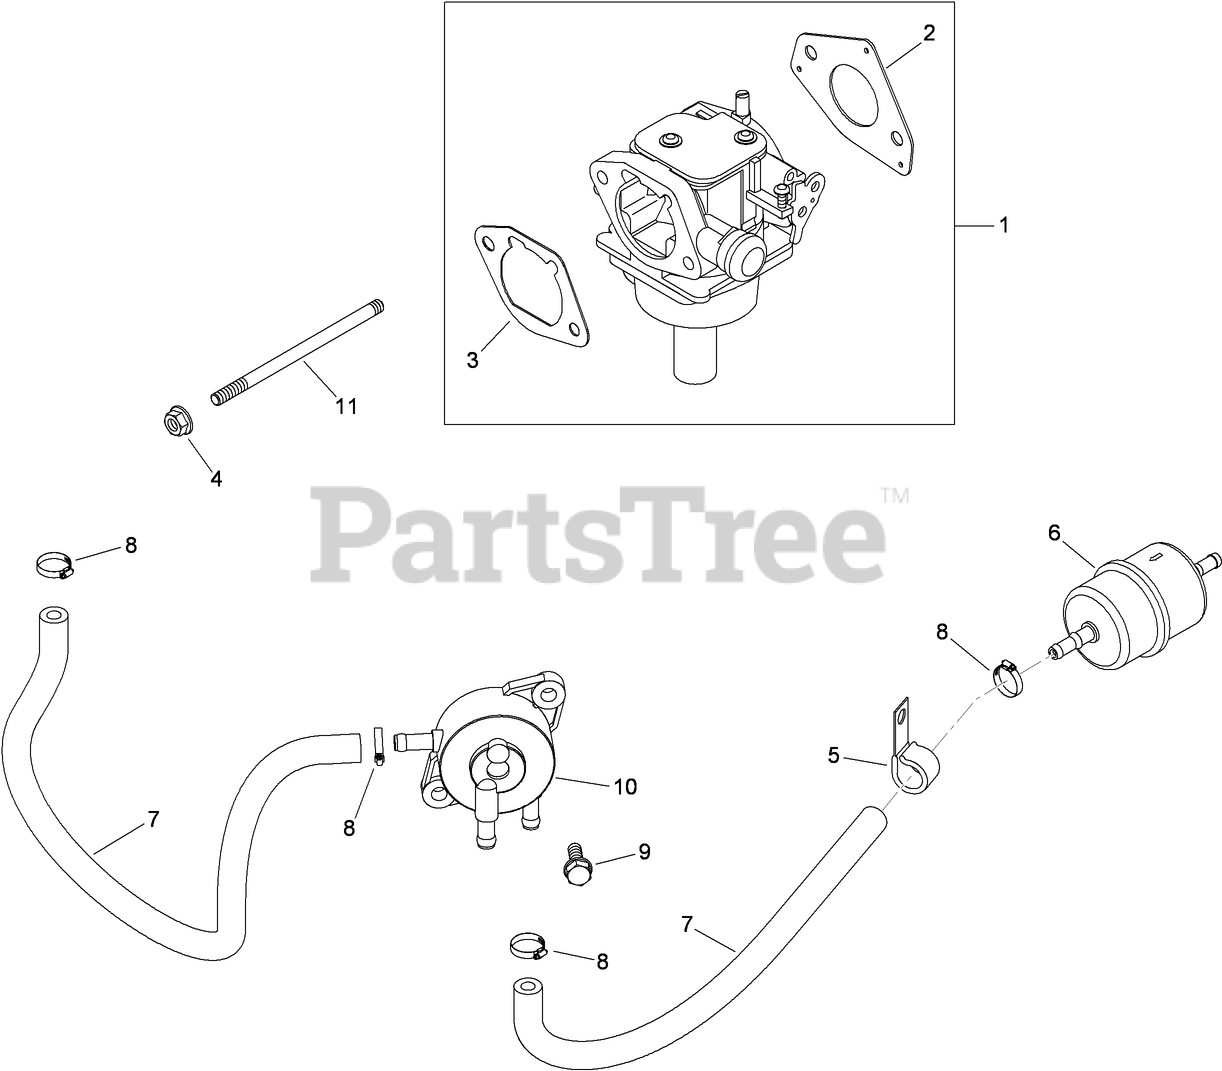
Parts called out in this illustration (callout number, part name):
1	CARBURETOR KIT-19mm KEIHIN (INCLUDES REF 1:1, 1:2, 1:3, 1:4, 1:5)
2	GASKET-CARBURETOR
3	GASKET-BASE, AIR CLEANER
4	NUT-FLANGE (M6X1.0)
5	CLIP-CABLE
6	Filter-Fuel
7	LINE-FUEL (24-CUT TO LENGTH)
8	CLAMP-HOSE, SPRING (1/2)
9	SCREW-TAP (M6X1.7X18)
10	PUMP-FUEL
11	STUD (M6X1.0X106)
